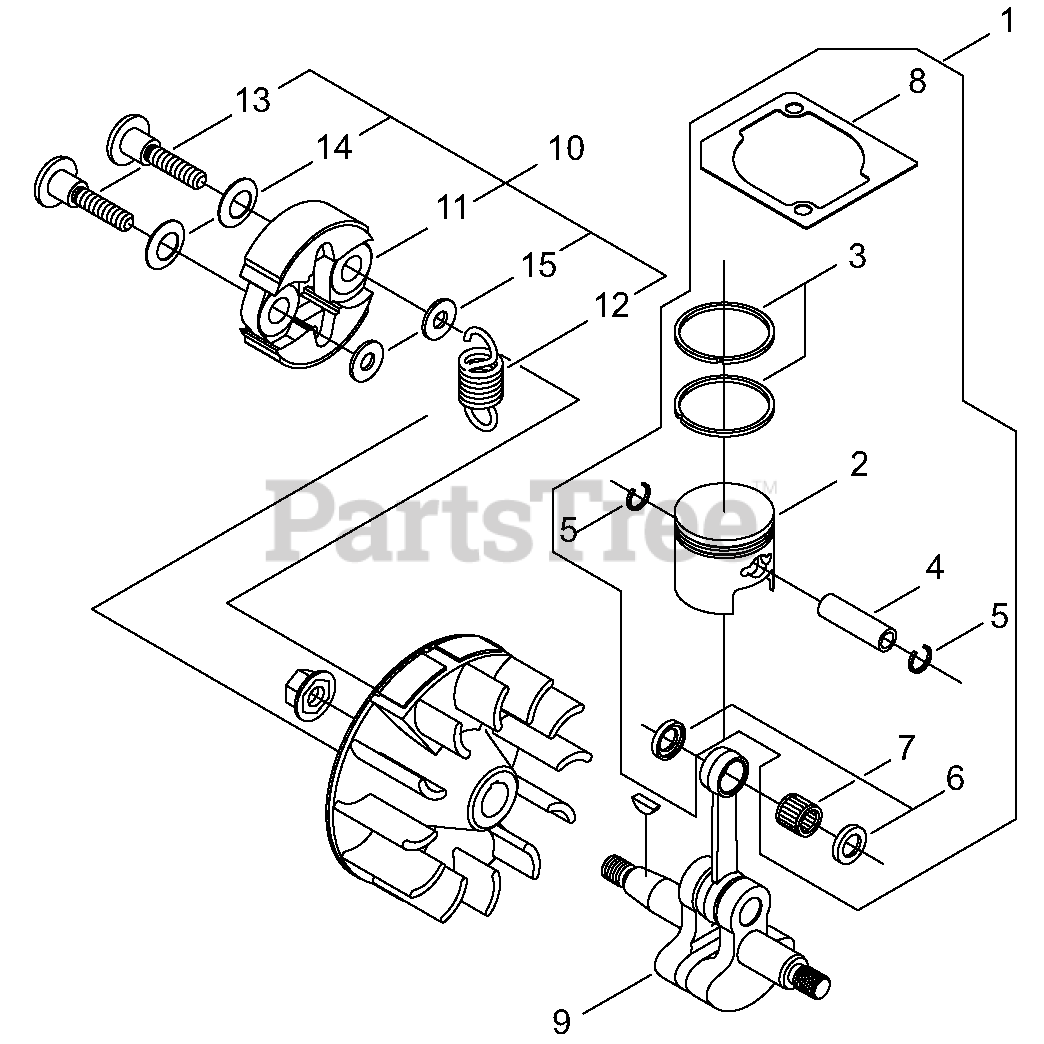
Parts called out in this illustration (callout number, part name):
1	PISTON KIT
2	PISTON
3	RING, PISTON
4	PIN, PISTON 8
5	RING, SNAP
6	WASHER, THRUST 8
7	BEARING, NEEDLE 8
8	GASKET, CYLINDER
9	CRANKSHAFT
10	CLUTCH ASSY
11	SHOE, CLUTCH
12	SPRING, CLUTCH
13	BOLT, CLUTCH
14	WASHER, SPRING
15	WASHER 6 MM
